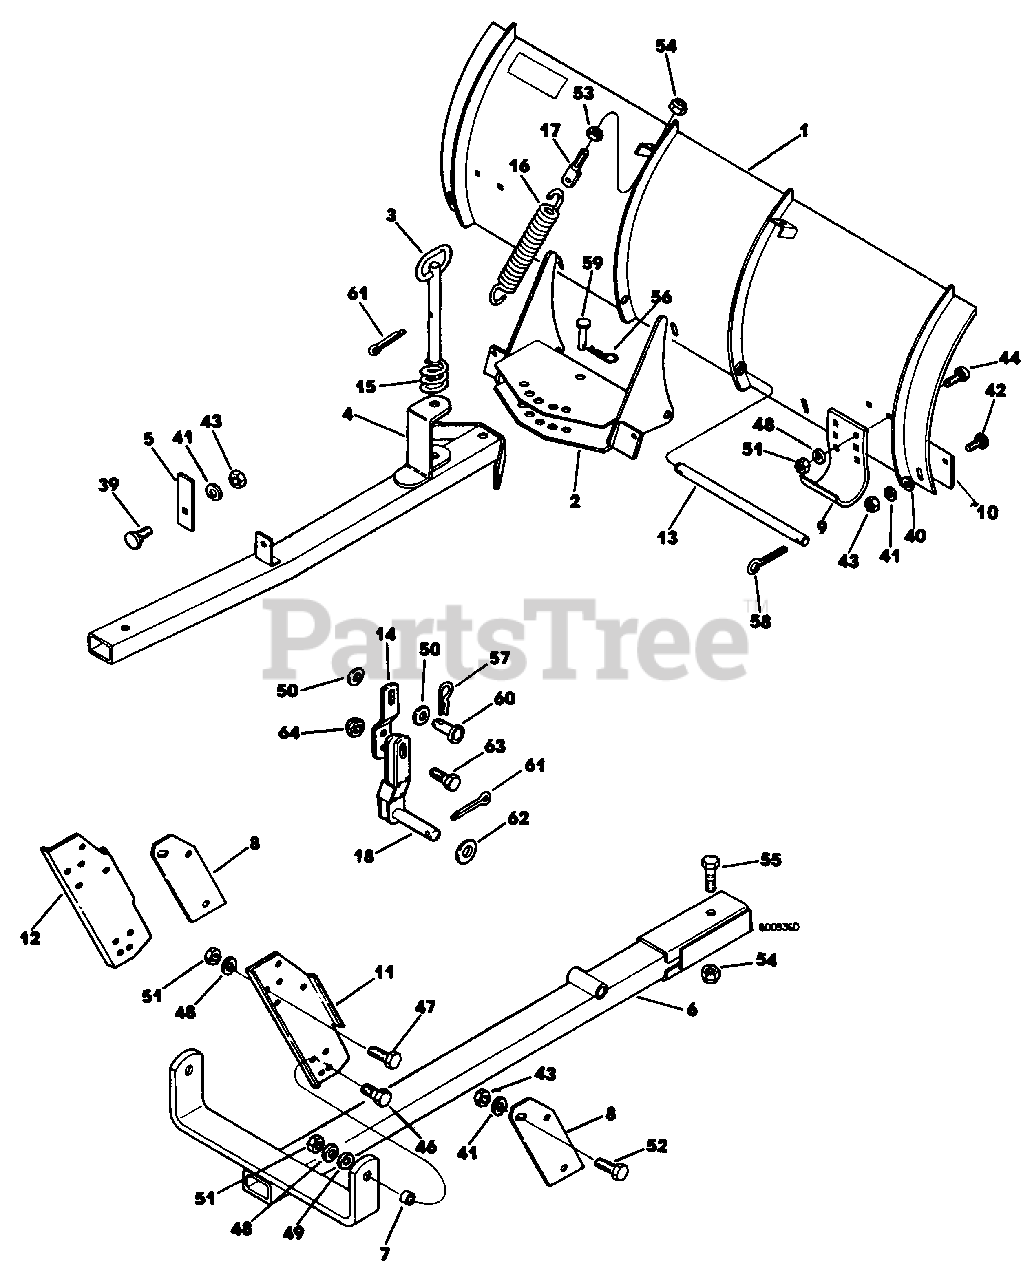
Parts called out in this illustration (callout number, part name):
1	Snow Blade Assembly W/Decal
2	Trip Plate Assembly
3	Hitch Pin Assembly
4	Front Frame Assembly
5	Frame Stop
6	Rear Frame Assembly
7	Pivot Spacer
8	Hanger Plate
9	Shoe
10	Scraper Blade
11	Mounting Bracket-R.H. (Yard Tractor Only)
12	Mounting Bracket-L.H. (Yard Tractor Only)
13	Trip Pin
14	Link-Reversing
15	Spring
16	Spring
17	Spring Adjusting Bolt
18	Lift Link Assembly
39	Bolt, Wafer Hd. Short Square Neck Plated
40	Washer, Flat SAE 5/16 Plated
41	Washer, Lock 5/16 Plated
42	Bolt, Carriage 5/16-18 x 1" Plated
43	Nut, Hex 5/16-18 Plated
44	Bolt, Carriage 3/8-16 x 1" Plated
46	Cap Screw, Hex Hd. 3/8-16 x 1-1/4 Plated, Grade 5
47	Cap Screw, Hex Hd. 3/8-16 x 1" Plated, Grade 5
48	Washer, Lock 3/8 Plated
49	Washer, Flat SAE 3/8 Plated
50	Washer, Flat SAE 7/16 Plated
51	Nut, Hex 3/8-16 Plated
52	Cap Screw, Hex Hd. 5/16-18 x 1" Plated, Grade 5
53	Nut, Hex Jam 1/2-13 Plated
54	Nut, Hex Cone Lock 1/2-13 Plated
55	Cap Screw, Hex Hd. 1/2-13 x 2-1/2 Plated, Grade 5
56	Spring Clip
57	Spring Clip
58	Pin, Cotter 3/16 x 1-1/2 Plated
59	Clevis Pin
60	Clevis Pin
61	Pin, Cotter 1/8 x 1-1/4 Plated
62	Washer, Flat SAE 3/4 Plated
63	Cap Screw, Hex Hd. 7/16-14 x 1-1/2 Plated, Grade 5
64	Nut, Hex Cone Lock 7/16-14 Plated
